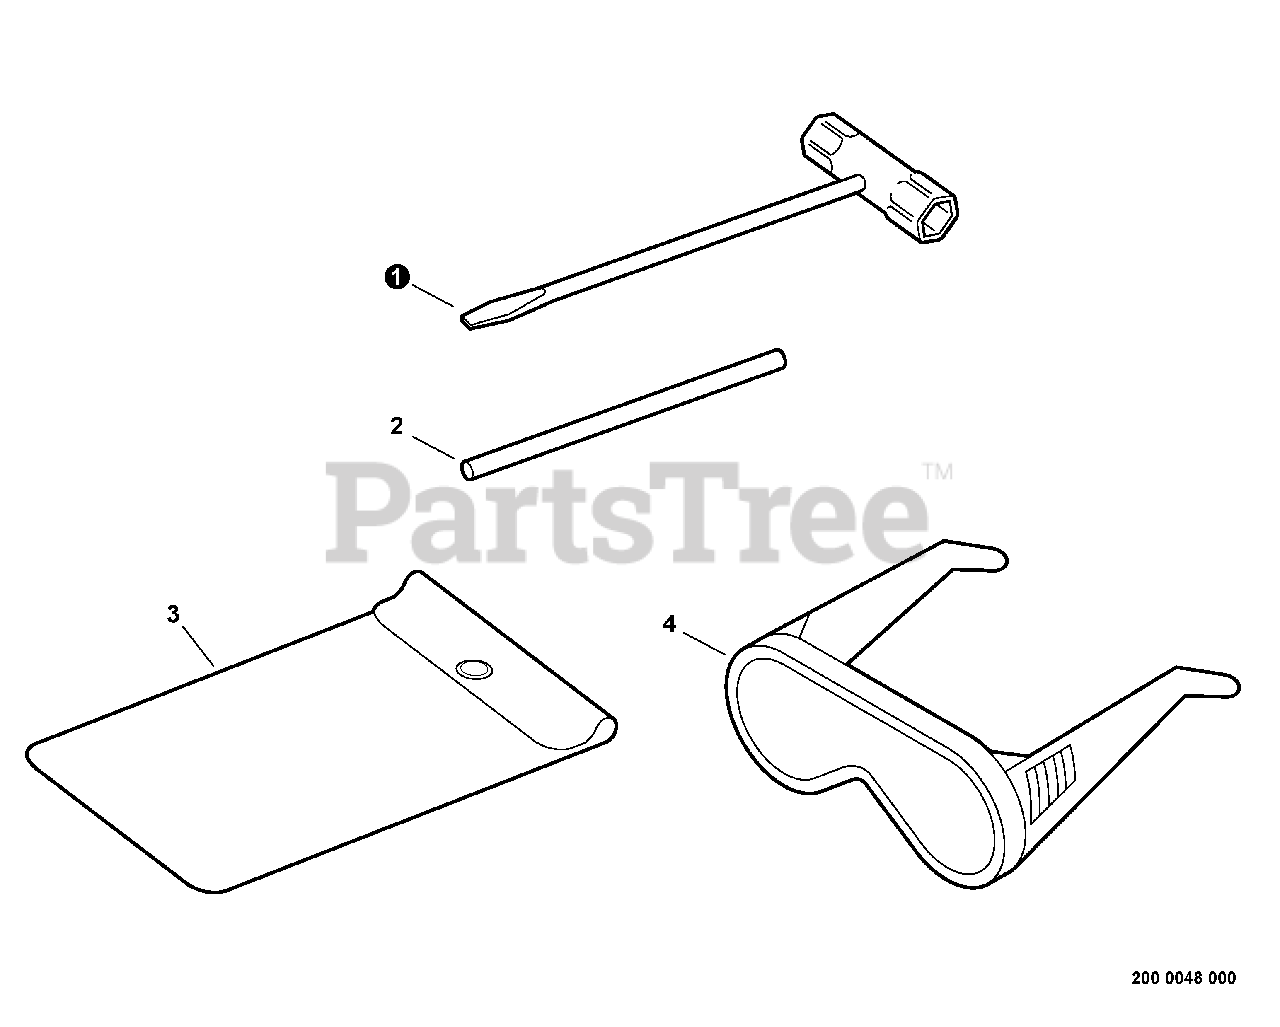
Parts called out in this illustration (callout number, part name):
1	T-WRENCH - 17X19mm
2	ROD, LOCKING - 5X120mm
3	BAG, TOOL
4	GOGGLES
